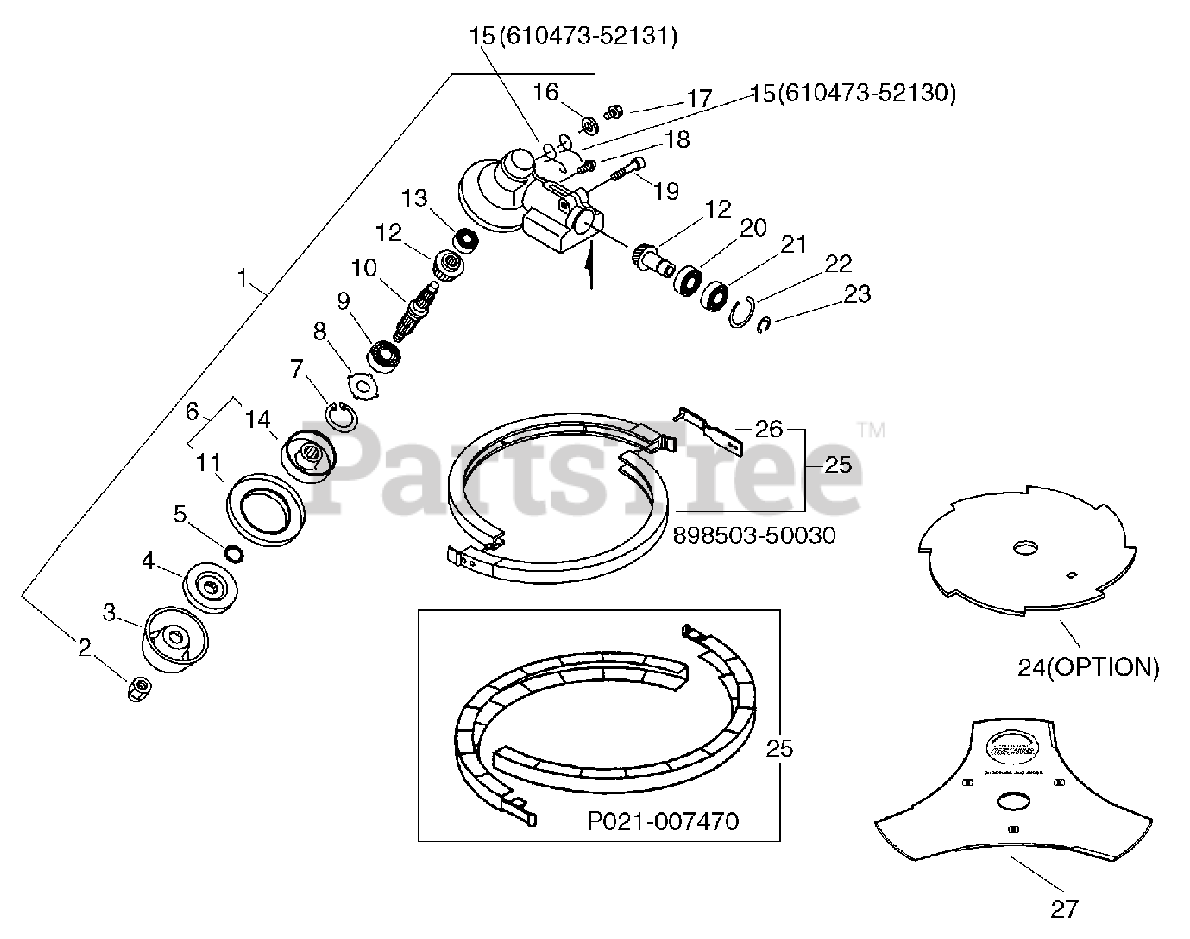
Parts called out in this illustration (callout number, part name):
1	GEAR CASE ASSY
2	NUT, LOCK 10 - NYLON INSERT
4	PLATE, ADAPTOR - LOWER
5	O-RING 12 MM
6	PLATE, ADAPTER - UPPER
6	ADAPTOR PLATE SET
6	RETAINER ASSY, BLADE
7	RING, SNAP Ø32
9	BEARING, BALL 6201
10	SHAFT, GEAR
11	PLATE, ADAPTOR - LOWER
12	GEAR SET
13	BEARING, BALL 629
14	PLATE, ADAPTOR - UPPER
14	RETAINER, BLADE
15	SPRING, TORSION
16	WASHER 8.5×18×0.8T
17	BOLT 8×6
17	BOLT M8×8
18	SCREW 5×10
19	BOLT 6×30
20	BEARING, BALL 6001
21	BEARING, BALL 6001
21	BEARING, BALL 6001Z
22	RING, SNAP 28
23	RING, RETAINING - 12
24	BLADE, 10" 80-TOOTH
25	SCABBARD KIT
25	SCABBARD
26	CLIP, SCABBARD
27	BLADE, 3-TOOTH
27	BLADE, 10" 3-TOOTH
